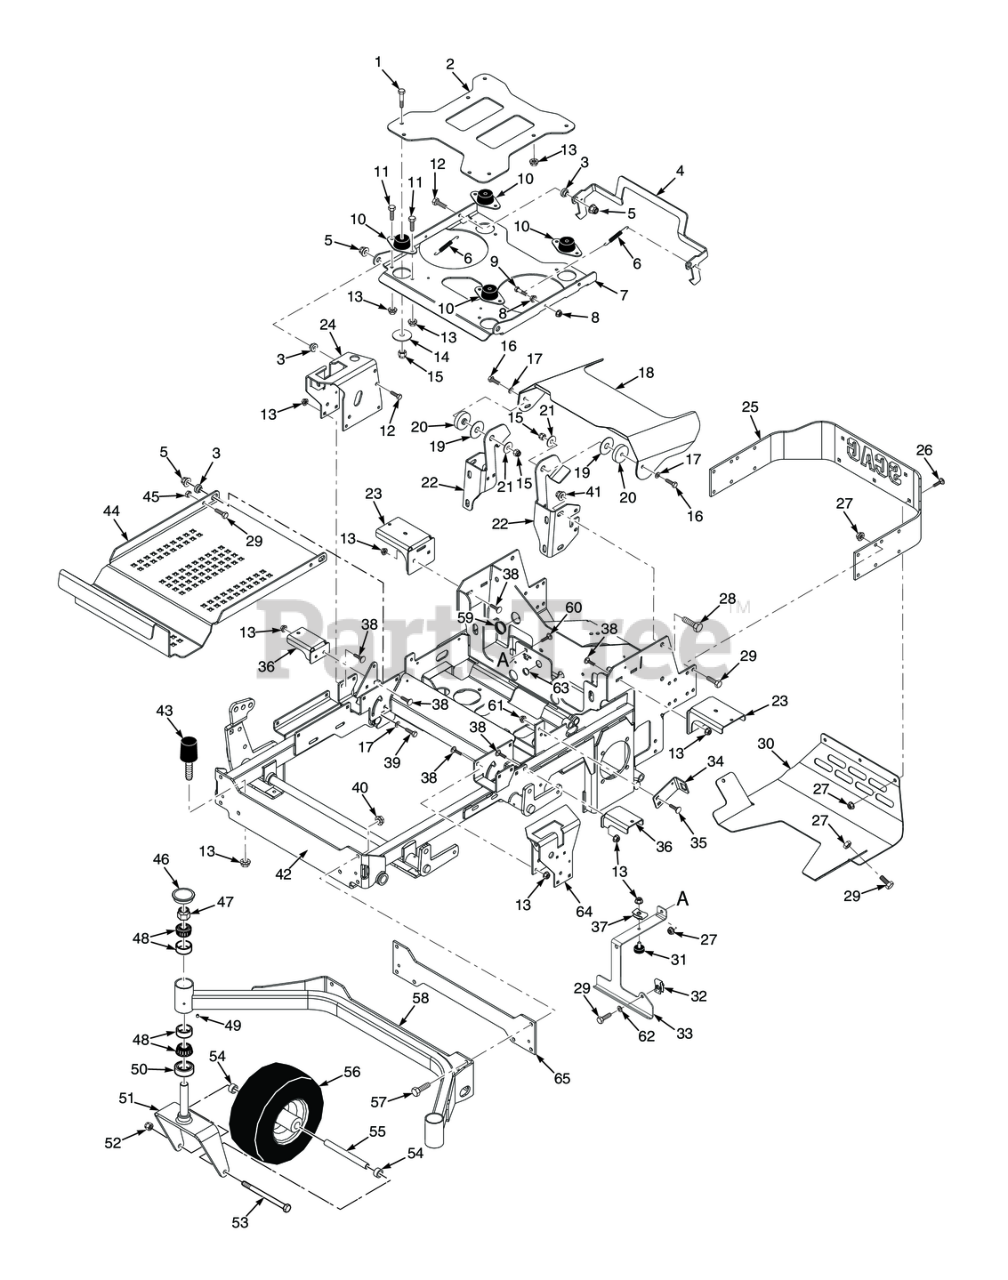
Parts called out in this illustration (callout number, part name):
1	Bolt, Hex Head 3/8-16 x 2-1/4" - 61"
2	Seat Plate w/decal
3	BUSHING, SPEED ADJUSTMENT LEVER
4	Seat Latch
5	Nut, Flange Elastic Stop Nut, 3/8-16
6	Spring, Seat Latch
7	Plate, Seat Mounting w/decals
8	NUT, 1/4-20 SERRATED FLANGE HEX HEAD
9	SERR. FLG. HEX HEAD CAPSCREW, 5/16-18 X 3/4
10	Isolator, Seat
11	BOLT, SERRATED FLANGE HEX HEAD 5/16-18 X 3/4"
12	Bolt, Hex Head 3/8-16 x 1-1/4", Kawasaki FX / FS
13	Nut, Serrated Flange 5/16-18 (Right Front Engine Mounting, Briggs and Kohler Only)
14	Flatwasher, 3/8-.406 x 2.25" x .1875
15	HEX NUT, ELASTIC STOP LOCK, 3/8-16
16	Bolt, Hex Head 3/8-16 x 1-3/4" (Kohler EFI)
17	Flatwasher, 3/8" Special (.391 x .938 x .105)
18	Hood Assembly
19	Disc, Anti-Friction
20	Spacer, Hood
21	Flatwasher, 3/8-.406 x 1-1-1/2 x 7 Gauge
22	ROPS Mount, RH
22	ROPS Mount, LH
23	Mounting Bracket, Fuel Tank Rear
24	Control Plate w/decal, RH
25	Bumper, Rear
26	Carriage Bolt, 3/8-16 x 1.0"
27	NUT, 3/8-16 SERRATED FLANGE HEX HEAD
28	Bolt, Hex Head 1/2-13 x 1-1/4"
29	Bolt, Hex Head, 3/8-16 x 1 Gr. 5
30	Plate, Skid
31	Bumper, Rubber 5/16-18 x 5/8"
32	U-Nut, 3/8-16 (short)
33	BATTERY HOLD DOWN
34	Bracket, Operator Presence Switch
35	Serr. Fl. Hex Head CPSCR, 1/4-20 x 3/4"
36	Mounting Bracket, Fuel Tank Front
37	Cable Clamp, Double
38	Bolt, 5/16-18 x .75 RHSN Carriage
39	Bolt, Hex Head, 3/8-16 x 1-1/2"
40	Nut, 7/16-14 Flange Elastic Stop
41	Nut, Elastic Stop 1/2-13, (STT-52 & STTII-52)
42	Main Frame Assembly w/decals (61")
43	Rubber Isolator
44	Footplate
45	HEX NUT, JAM 3/8-16
46	Cap, Grease
47	Nut, Hex Elastic Stop 1.0"-14
48	BEARING & CUP, TAPERED SPINDLE
49	Plug, 1/4-28 THD Form
50	Seal, 2.00" O.D. x 1.625" Bore
51	Yoke Weldment, (Black))
52	HEX LOCKNUT, ELASTIC STOP, 1/2-13
53	Bolt, Hex Head 1/2-13 x 9-1/2" (61V & 72A/VS)
54	Spacer, Caster Wheel
55	Sleeve, Caster Wheel (61V, 72A/VS)
56	Wheel Assy, 61V, 72V (Incl. 20, 54, 55)
57	BOLT, HEX HEAD, 7/16-14 X 1-1/4
57	HEX HEAD BOLT 7/16-14 X 1-1/2"
58	Caster Support Weldment (48"/52")
59	Bushing, Thick Panel Snap
60	Bolt, Carriage 3/8-16 x 3/4"
61	HEX, NUT, ELASTIC STOP LOCK, 1/4-20
62	Lockwasher, 3/8" Spring, Kawasaki FX / FS
63	Bushing, Thick Panel Snap - 1"
64	Control Plate w/decal, LH
65	Weight, Caster - Yamaha Models Only
